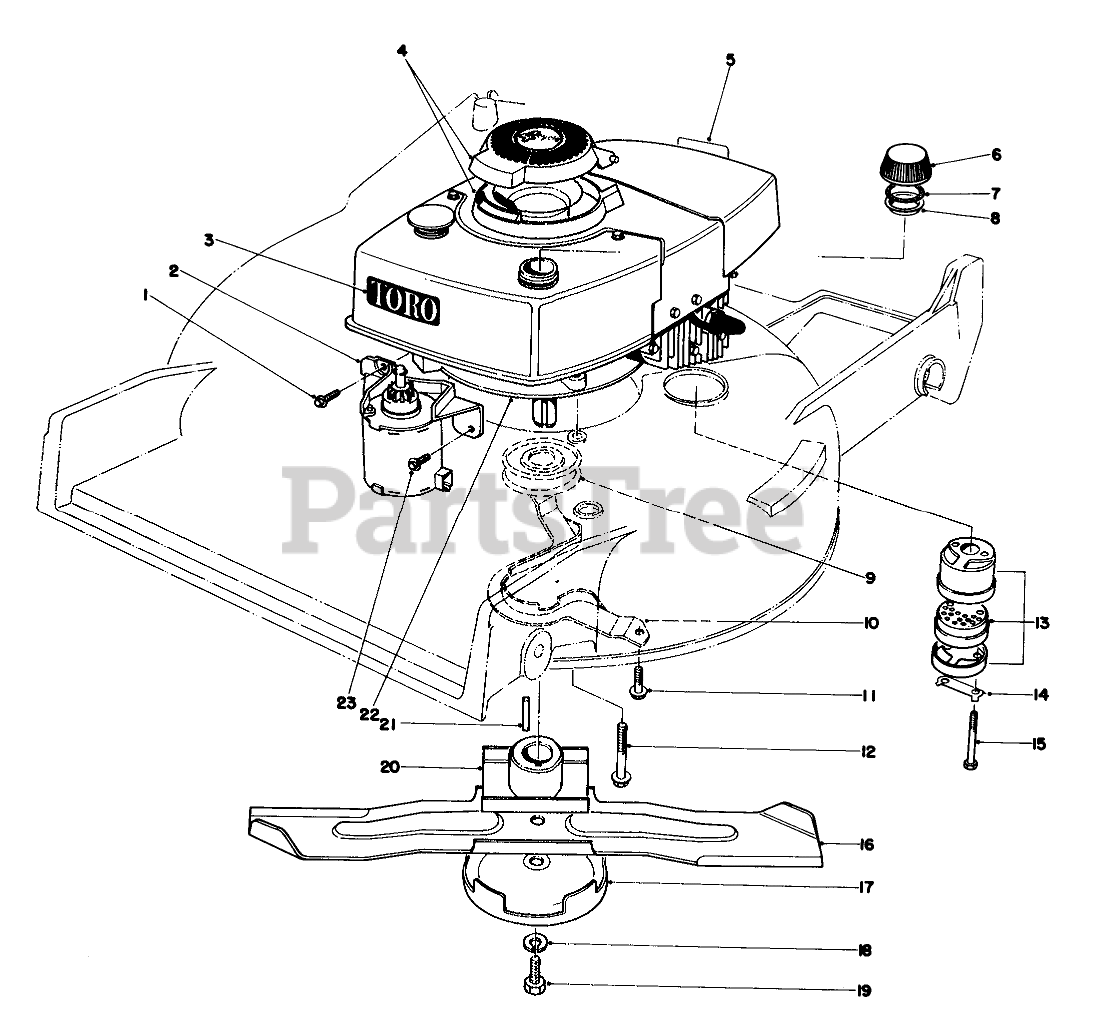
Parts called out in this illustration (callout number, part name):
1	Screw
2	Starter Motor
3	Decal Toro
4	COVER ASM
5	Decal-Maintenance
6	Gas Cap (Incl. Ref. #7 & 8)
7	GASKET
8	GAS CAP BAFFLE
9	Pulley
10	BELT GUIDE
11	Screw
12	SCREW-HWHTF
13	Muffler Assembly (Incl. Ref. #14 & 15)
14	CLIP - LOCKING
15	SCREW-HH
16	Blade
17	Anti Scalp Cup
18	WASHER-LOCK
19	BLADE SCREW
20	BLADE RETAINER WA(BLACK)
21	KEY-SQUARE
22	Engine
23	SCREW
